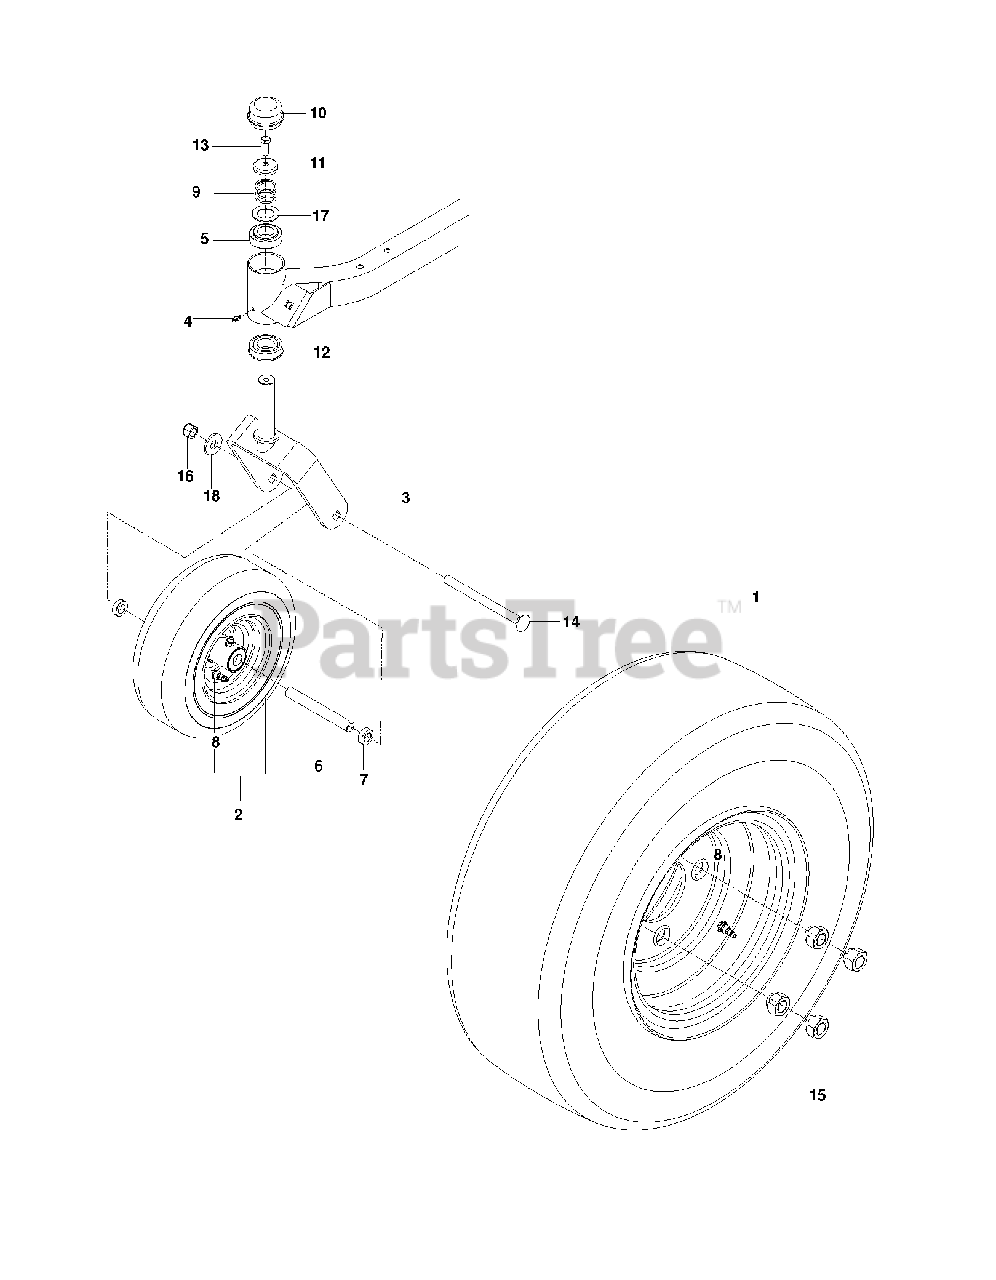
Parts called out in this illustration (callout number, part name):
1	WHEEL.18X7.50-8.K500.8X5.375
2	WHEEL.11X4-5.K404LG.5X3W/4.188
3	YOKE.CASTER.ORANGE
4	ZERK, 3/16, DRIVE IN
5	BUSHING, CASTER
7	SPACER, 5/16"
8	VALVE STEM TR-412
9	SPRING, CASTER
10	GREASE CAP
11	CASTER.PLUG
12	BEARING FLANGED
13	5/16-18X1 HHB G5W/NY
14	RHSNB 1/2-13 X 6.50 GR2 ZD
15	LUG NUT 1/2F
16	NUT 1/2-13 HEX CNTRLK GR 5 ZD
17	WASHER, 1.025 ID X 1.64
18	WASH USS FLAT 1/2
